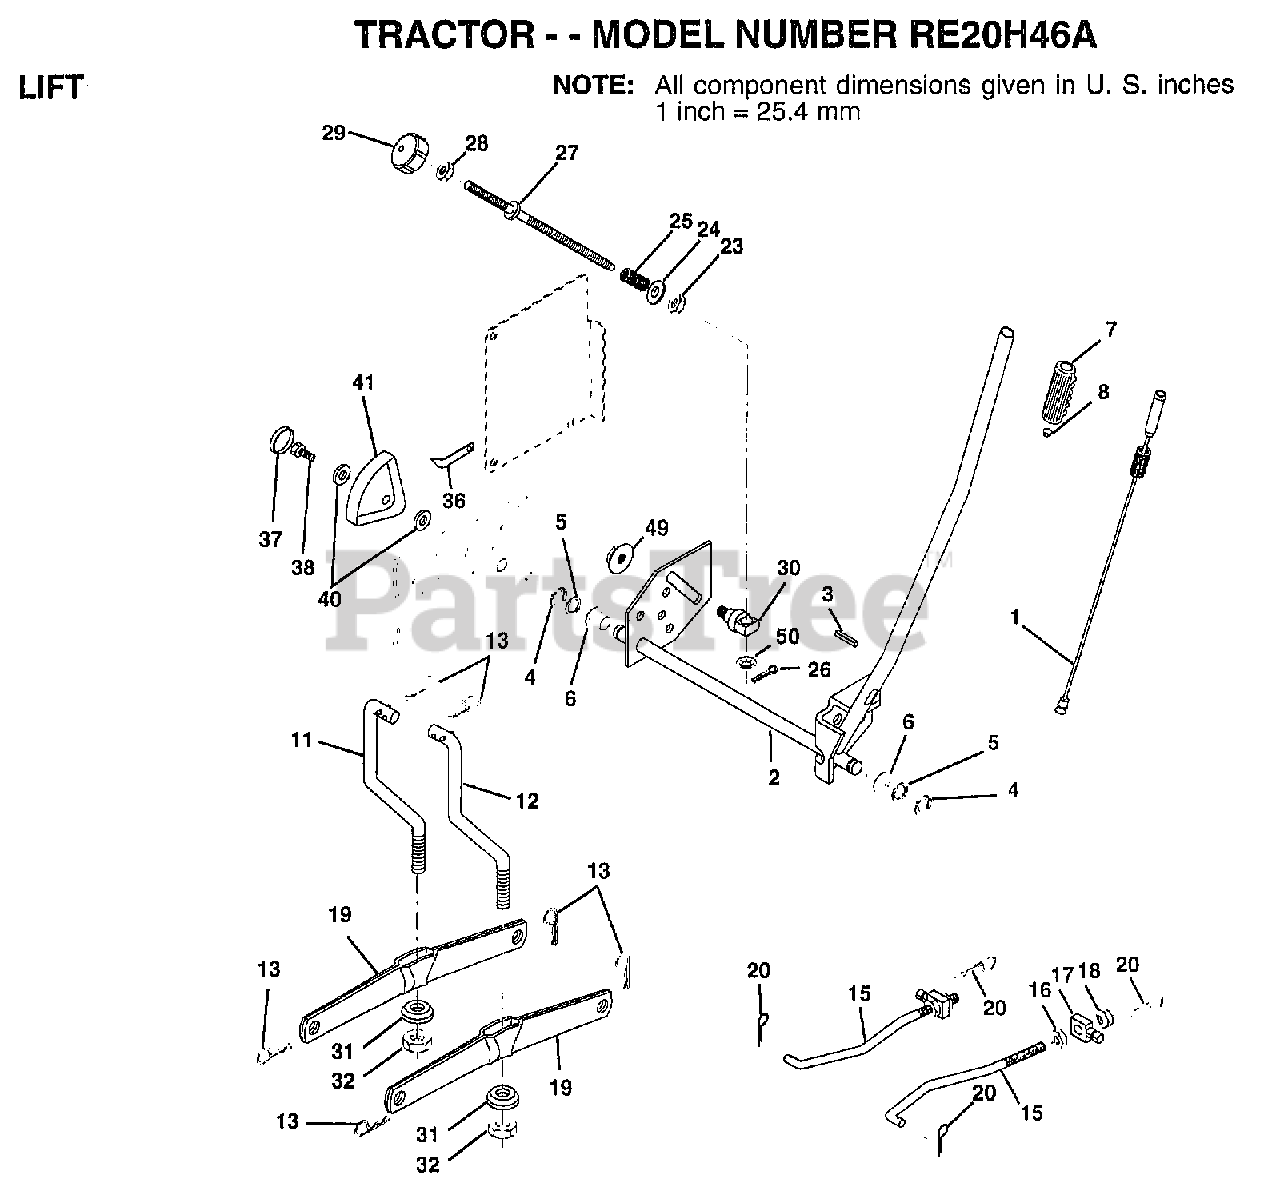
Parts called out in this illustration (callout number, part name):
1	LEVER ROD LT
2	LEVER ASSY LIFT.RH.
6	"BOLT,HEX"
7	GRIP HANDLE
10	SPRING T
11	LINK.LIFT.LH.GTV
12	LINK.LIFT.RH.GTV.
14	LEVER.ASM.LIFT.RH
15	LINK.FRONT
16	NUT
17	TRUNION
18	NUT LTV
19	ARM SUSP REAR
20	RETAINER SPRING
23	NUT T
24	WASHER
25	SPRING.COMP.INF.H
27	ROD.ADJ.LIFT
28	NUT
29	KNOB INF 3/8-16
30	TRUNNION
31	BEARING PVT LH
32	NUT.CROWNLOCK.3/8
36	POINTER-INDICAT
37	"PLUG,HOLE"
38	SCREW
39	STOP.OVER.CENTER
40	WASHER
41	HEIGHT INDICATOR
43	WASHER GT
44	BOLT
46	E-RING
47	WASHER
49	NUT.HXFLG.LOCK.
50	NUT PUSH M
